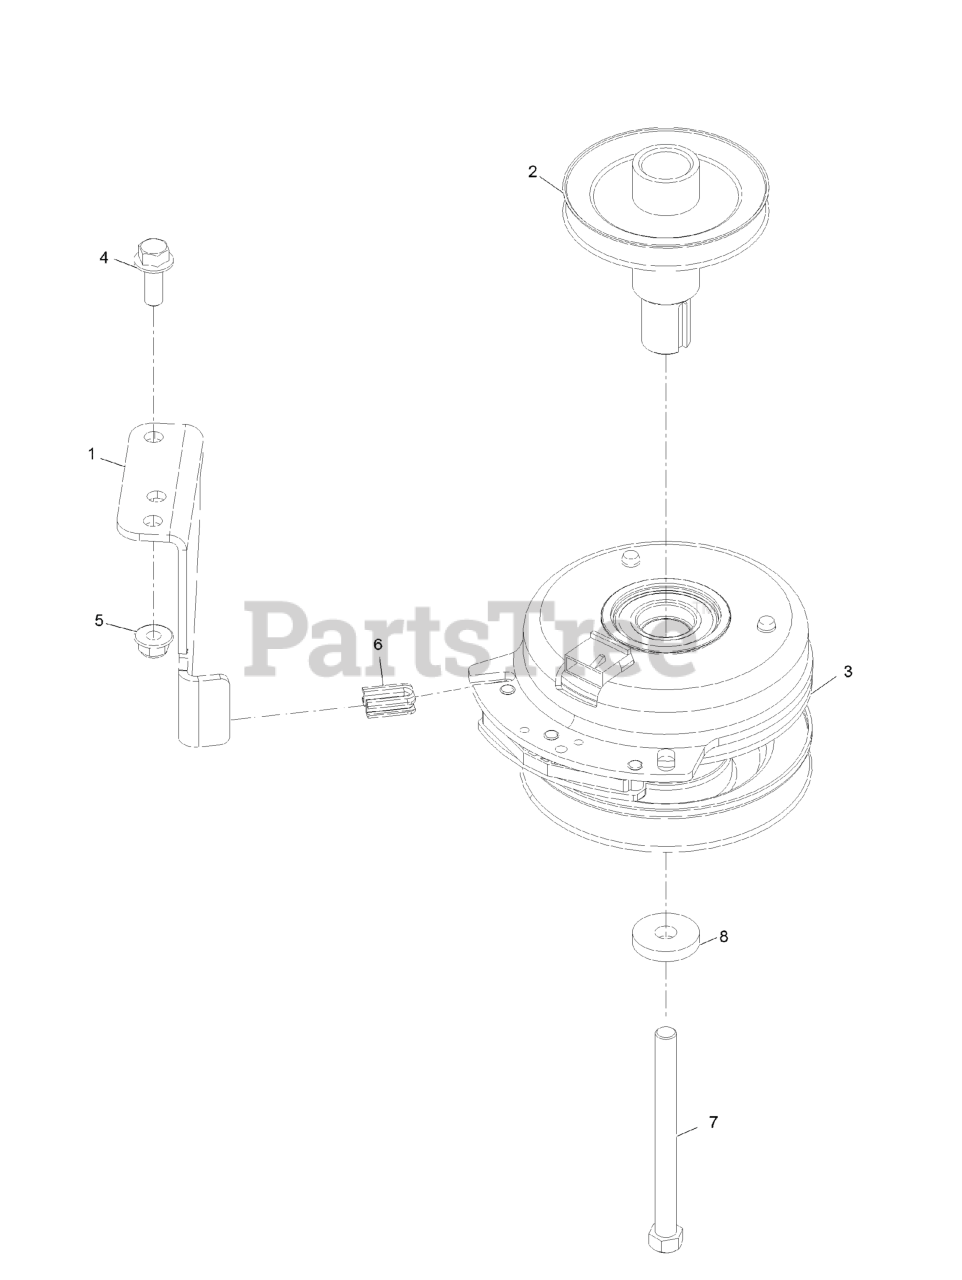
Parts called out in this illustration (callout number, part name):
1	STOP-CLUTCH (WIDE)
2	Pulley-Engine
3	CLUTCH-PTO
4	SCREW-HHF 3/8-16 X 1
5	NUT-HF, NI
6	ISOLATOR-CLUTCH
7	SCREW-HH
8	WASHER
